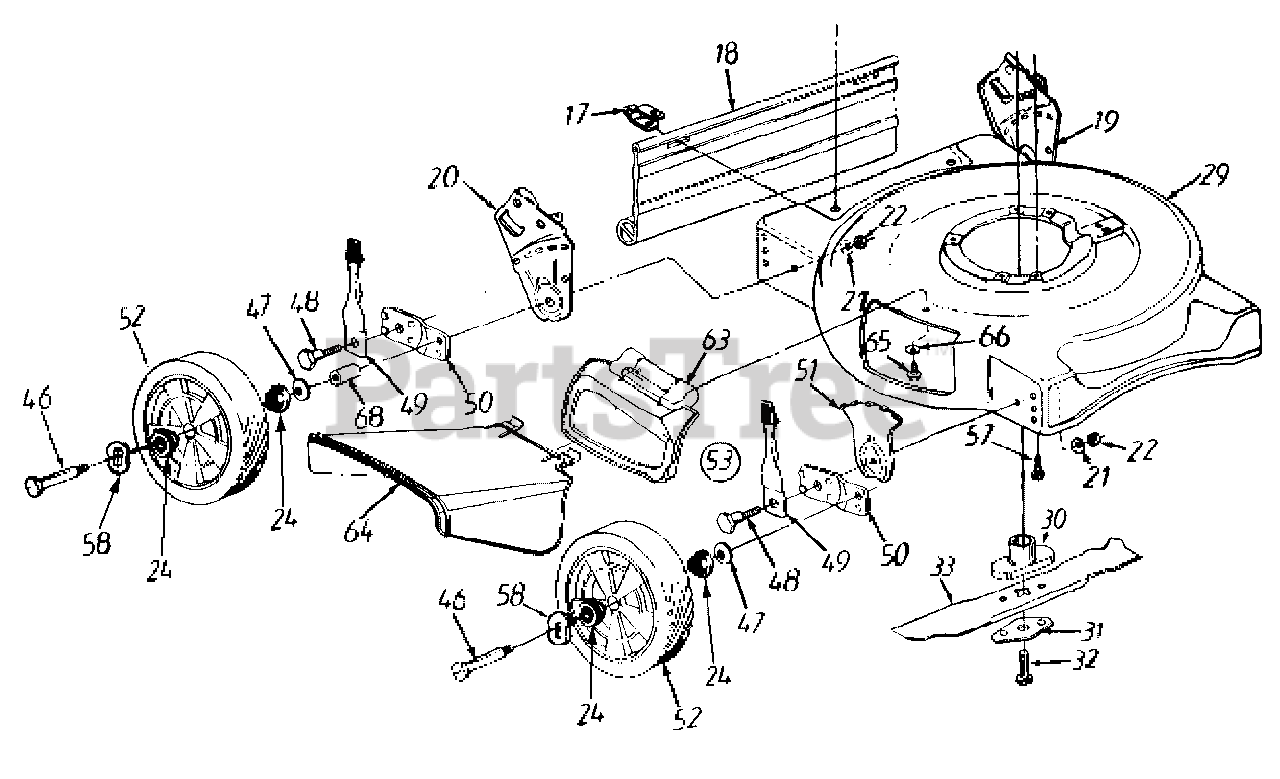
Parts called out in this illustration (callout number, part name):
17	Hinge Clip
18	Rear Flap
21	Bell Washer .39" ID x 1.38"
22	Hex Nut 3/8-16 Thd.
24	Bearing
29	Deck Assembly
30	Blade Adapter Kit
31	Blade Bell Support
32	Hex Bolt 7/16-20 x 1.5"
33	20" Mulch Blade
47	Bell Washer .400" ID x .88"
48	Shoulder Bolt
49	Spring Lever Ass'y w/Knob
51	Height Adj. Plate
52	Wheel Assembly
53	Height Adj. Ass'y. Comp. R.F. & L.R.
57	Hex Lock Washerhead Screw 3/8-16 x 1.0" Lg.
58	Wave Washer
63	Mulching Plug
64	Chute Deflector
66	Hex Washerhead TT Screw 1/4-20 x .5" Lg.
68	Spacer
